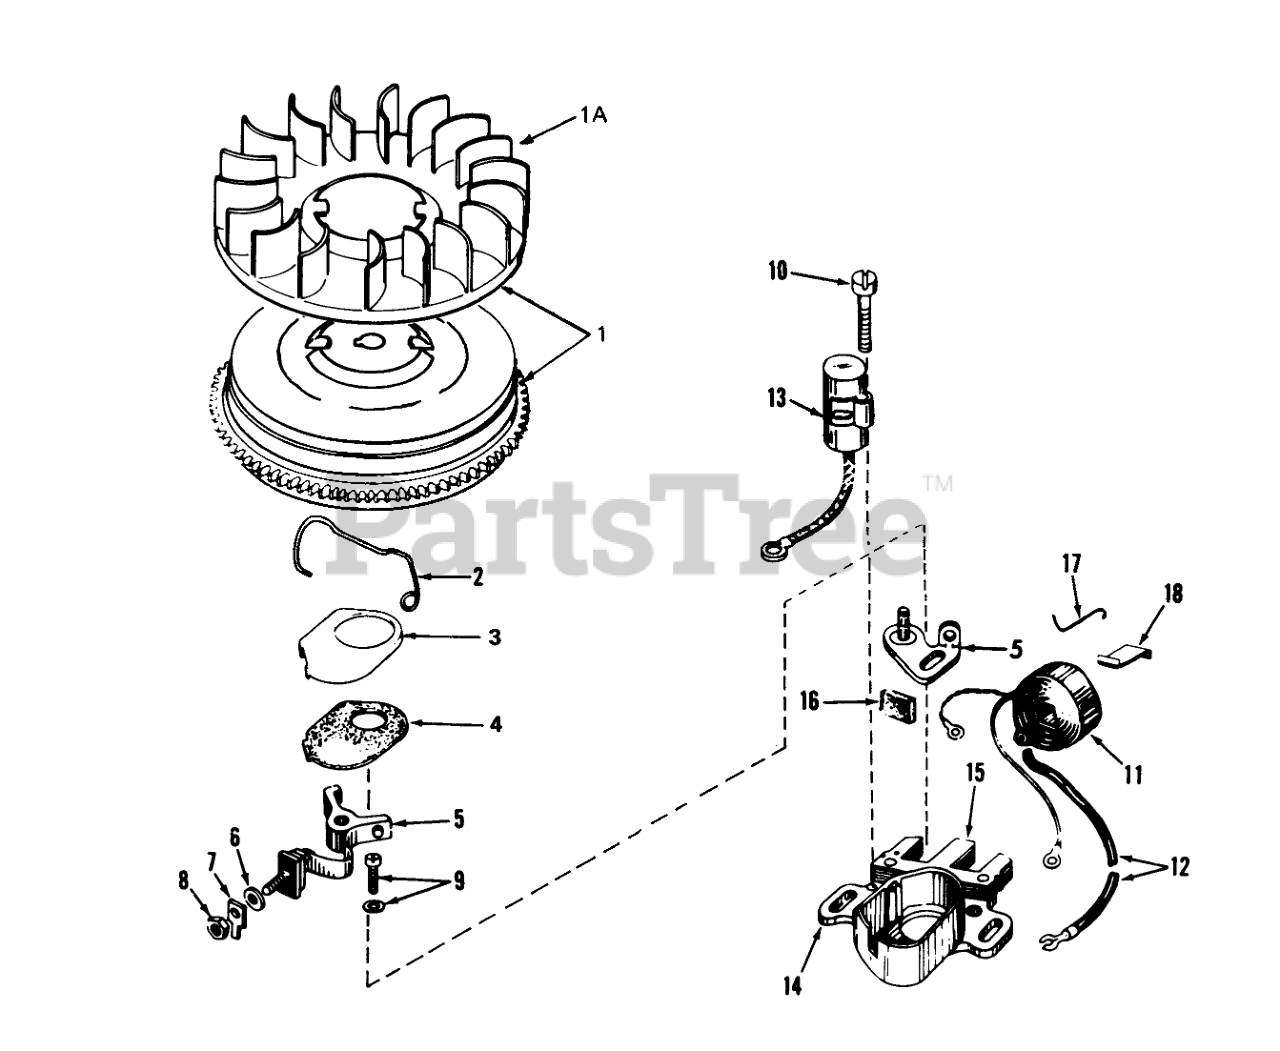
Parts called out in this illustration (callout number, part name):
1	Flywheel (Incl. Ref. #1A)
1A	Fan
2	Spring Breaker Box
3	Cover-Dust
4	Gasket, Dust Cover
5	Breaker Assy.
6	Washer
7	Terminal, Ground
8	DECAL
9	Breaker Screw
10	Condenser Screw
11	Coil Assy. (Incl. Ref. #12)
12	Wire, Lead
13	Condenser
14	Core & Plate
15	Stator Assy. (Incl. Ref. #2 thru 14, 16, 17 & 18)
16	Felt,Cam Wiper
17	Clip, Coil
18	Spring Coil Wedge
